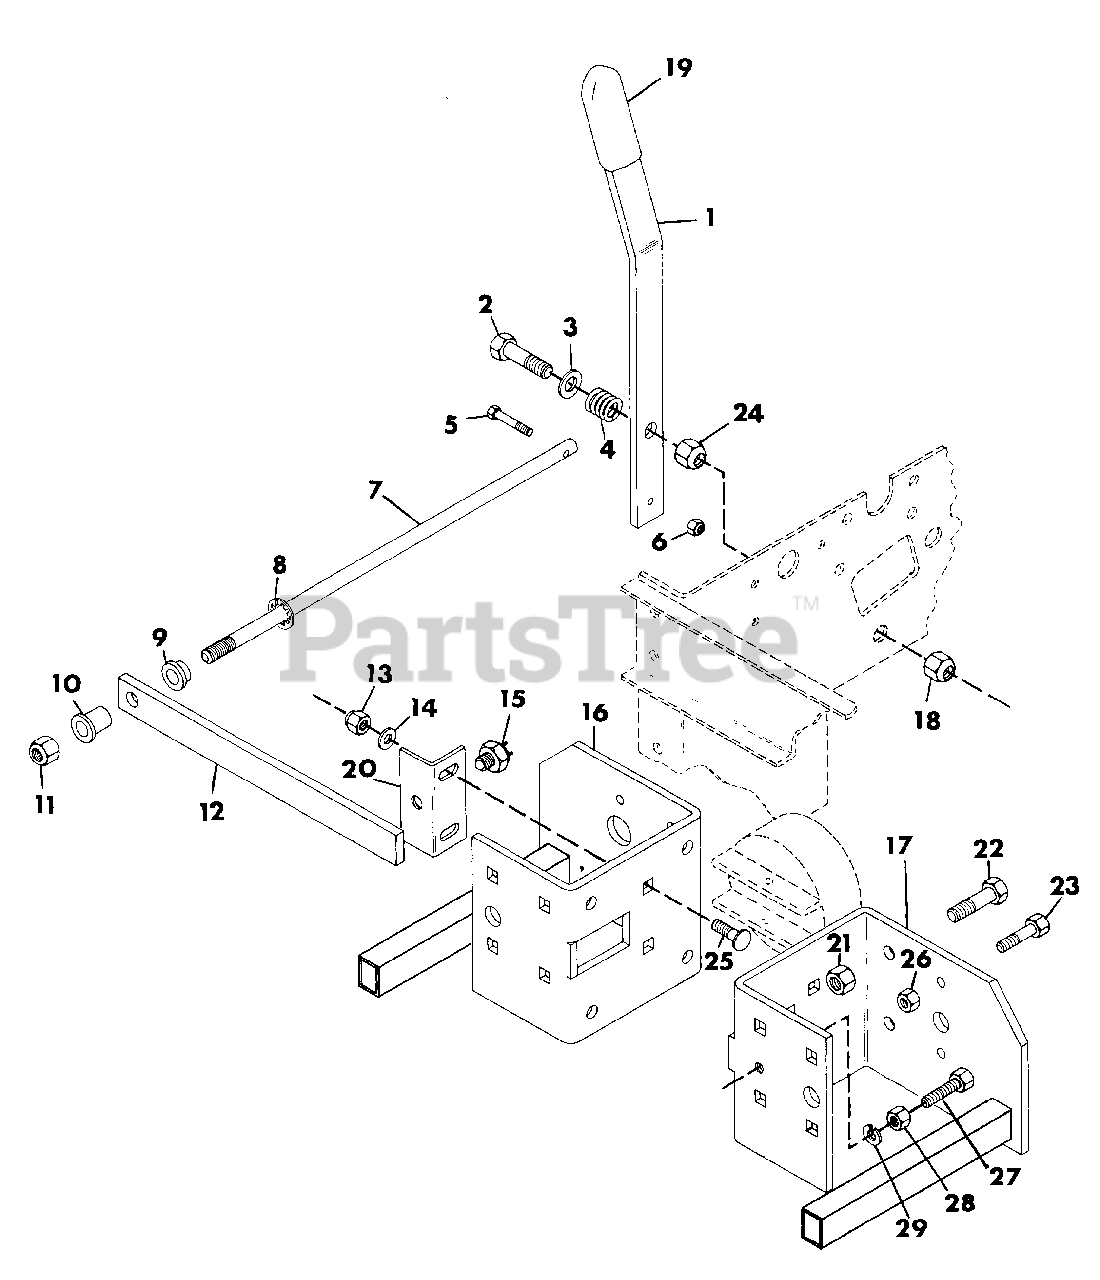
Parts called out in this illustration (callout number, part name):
1	LEVER, PTO
2	BOLT, HEX 1/2-13X2.500
3	WASHER, FLAT .531X1.062X.095
4	SPRING, COMPRESSION 1.00X.78X338 LB/IN
5	BOLT, HEX 1/4-20X1.25
6	NUT, LOCK 1/4-20
7	ROD, PTO
8	RING, RETAINING
9	BUSHING, .513X.750X.375
10	BUSHING, FWD-REV SLIDE ROD
11	NUT, LOCK 1/2-20
12	SPRING, FWD-REV CLUTCH
13	NUT, LOCK 5/16-18
14	WASHER, FLAT .344X.688X.065
15	SWITCH, NEUTRAL START
16	WELDMENT, R.H. MOWER BRACKET
17	WELDMENT, L.H. MOWER BRACKET
18	NUT, HEX 1/2-13
19	GRIP, HANDLE
20	BRACKET, INTERLOCK SWITCH
21	NUT, RIM
22	BOLT, HEX 1/2-20X1.50
23	BOLT, HEX 3/8-16X1.00
24	NUT, JAM 1/2-13 HEX
25	BOLT 5/16-18X.875 RD HD SQ NK
26	NUT, LOCK 3/8-16
27	BOLT, HEX 3/8-16X2.00
28	NUT, JAM 3/8-16 HEX
29	WASHER, LOCK 3/8 REG.
